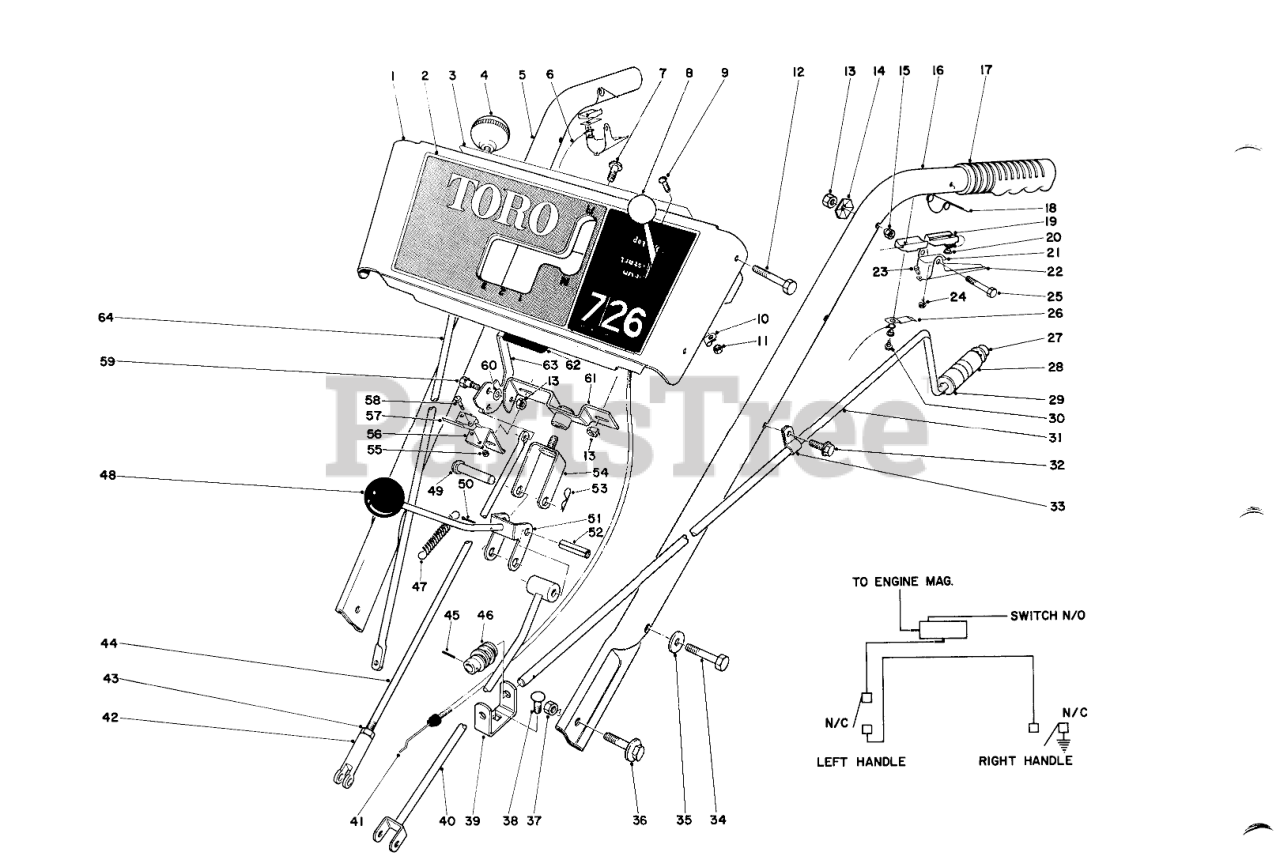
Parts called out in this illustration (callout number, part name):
1	Escutcheon Plate (Incl. Ref. #2 & 3)
2	Decal-Escutcheon
3	Decal
4	KNOB-LEVER
5	Handle Right
6	Wire Harness
7	Screw, Machine
8	KNOB-CONTROL
9	SCREW-PPH
10	Clip
11	Nut
12	SCREW-HH
13	NUT-LOCK
14	Washer
15	NUT-CAP
16	Handle-Left
17	Grip Handle
18	INTERLOCK SPRING
19	Insulator
20	WASHER INSULATOR
21	INTERLOCK CONTACT
22	Safety Lever
23	Rivet Plastic
24	SCREW-HWHTF
25	SCREW-HH
26	CONTACT BRACKET
27	Speed Nut
28	Chute Control Grip
29	WASHER-FLAT
30	Screw
31	ROD CHUTE CONTROL
32	Hex Hd. Screw
33	R-CLAMP
34	SCREW-HH
35	WASHER-FLAT
36	SCREW-HHF
37	NUT-HEX
38	SCREW-CARR
39	WORM BRACKET
40	Trunnion
41	Throttle Contrl
42	Clevis
43	NUT-HJ
44	Drag Link
45	PIN-SPRING
46	GEAR-WORM, CHUTE
47	CONT ROD SPRING 0
49	PIN-CLEVIS
50	PIN-COTTER
51	Rod Shift
52	PIN-ROLL
53	PIN-HAIR
54	Pivot Bracket
55	NUT-LOCK, NI
56	Bracket Switch
57	MICRO SWITCH
58	SCREW-HEAD, PAN
59	SCREW-SHOULDER
60	WASHER-PLAIN
61	SWIVEL BLOCK WA
62	AUGER CLUTCH HND GRIP
63	Auger Clutch Handle
64	Rod Wheel Clutch
